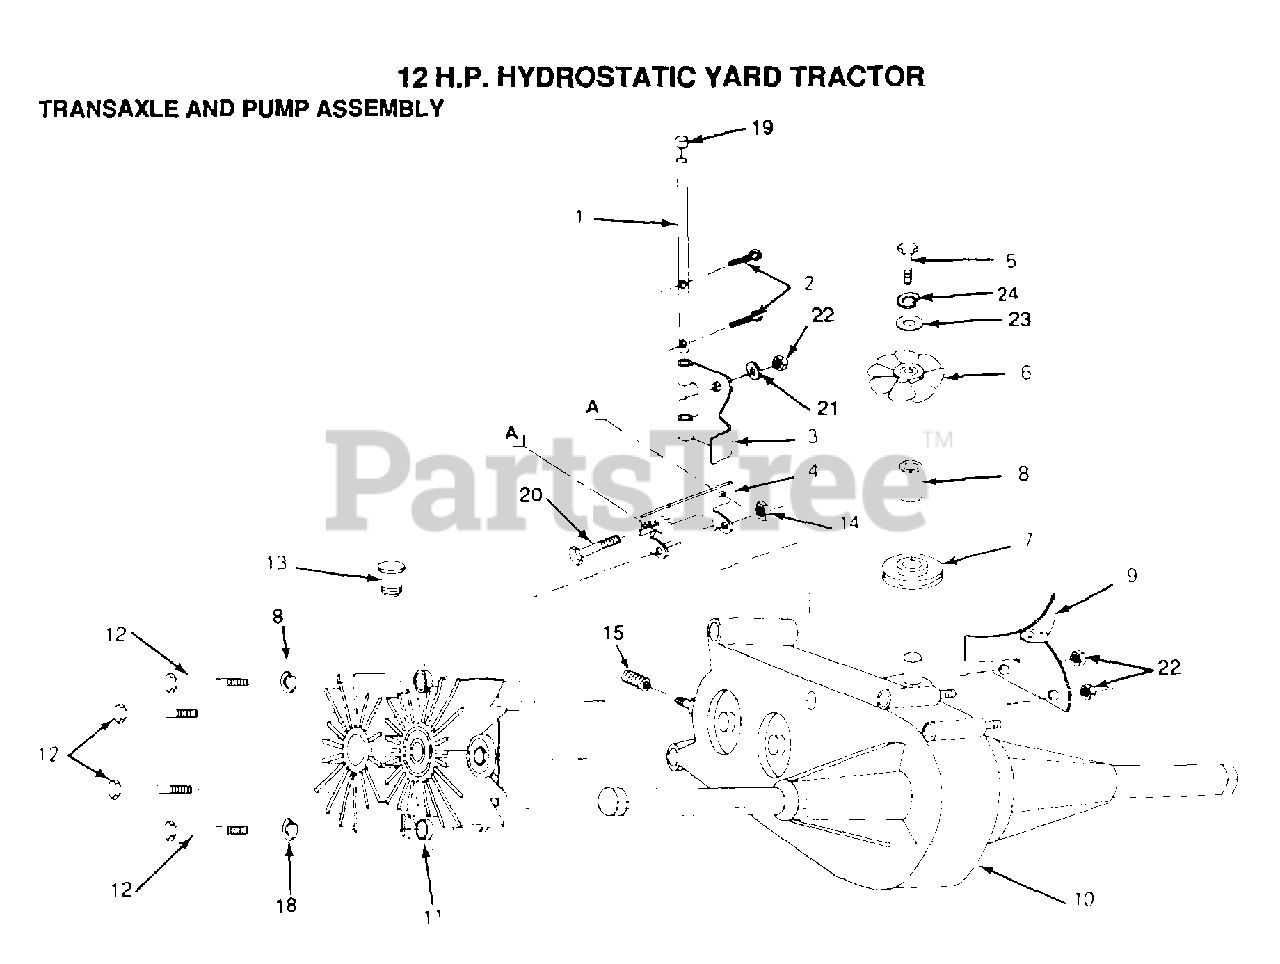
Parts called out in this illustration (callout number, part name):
4	BRACKET
6	FAN
7	PULLEY TRANSAXLE
8	STANDOFF
9	GUARD ASSY
12	BOLT
13	PUMP.2003081.
15	SPRING
18	LOCKWASHER
19	PLUNGER CAP T
20	BOLT T
21	WASHER T
23	WASHER
24	LOCKWASHER
